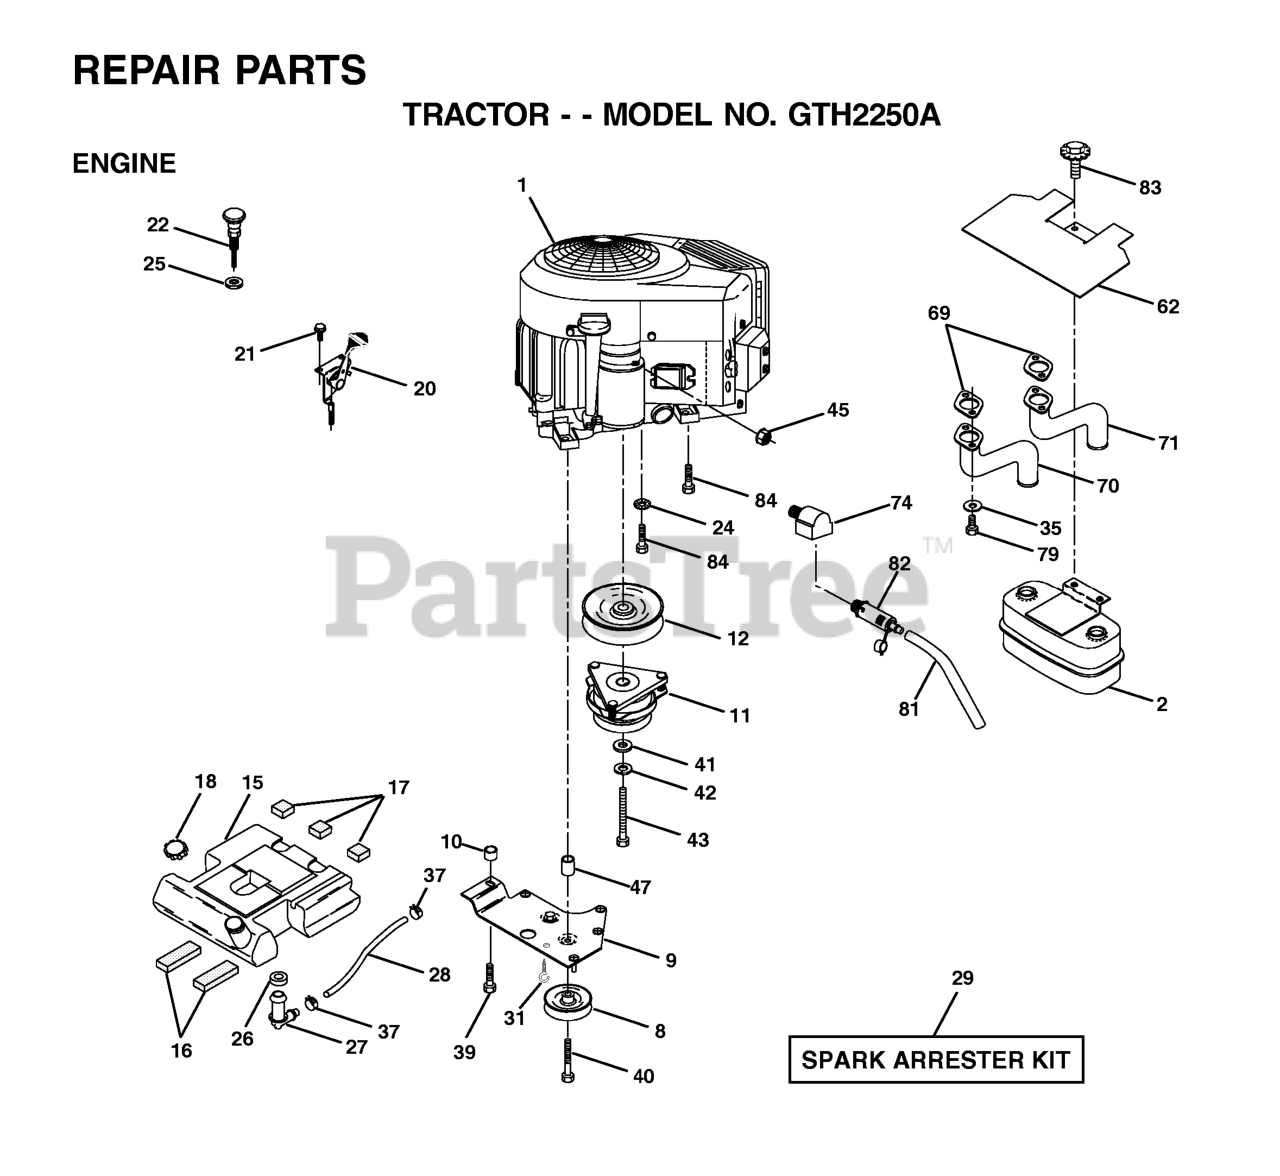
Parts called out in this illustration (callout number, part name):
2	MUFFLER.TWIN.CYL.LOW.TONE
8	RP.IDLER GROOVED
9	KEEPER ASM BELT ENGINE
12	PULLEY ENG VGT ELECT CLUTCH
15	FUEL TANK 3.5G
16	PAD IDLER TI
17	PAD-SPACER LT
18	CAP, FUEL GUAGE
20	THROTTLE CABLE
21	SCREW
22	REPL BY 532 1754-40
24	LOCKWASHER
25	Nut Keps 3/8 - 24 UNF
26	BUSHING OUTLET T
27	STEM FUEL TANK
28	FUEL LINE
29	KIT.SPARK ARRESTOR 794945 B&S
35	WASHER.LOCK.HVY.HLCL.SPR.5/16
37	HOSE CLAMP
39	SCREW TT 3/8-16X2-1/4 UNC
40	Screw TT 3/8-16 x 4 unc
42	LOCKWASHER
43	BOLT HEX 7/16-20X4-1/4"
45	NUT
62	RP SHIELD HEAT MUFFLER
69	GASKET.MUFFLER
70	TUBE.EXHAUST.B&S.VGT.LH
71	TUBE.EXHAUST.B&S.VGT.RH
74	ELBOW STREET BRASS
79	SCREW
81	TUBE, DRAIN OIL ASM.
82	PLUG, OIL DRAIN EASY
83	BOLT.5/16-18UNCX3/4 W/SEMS.BLK
84	SCREW 3/8-16 X 1-1/2
